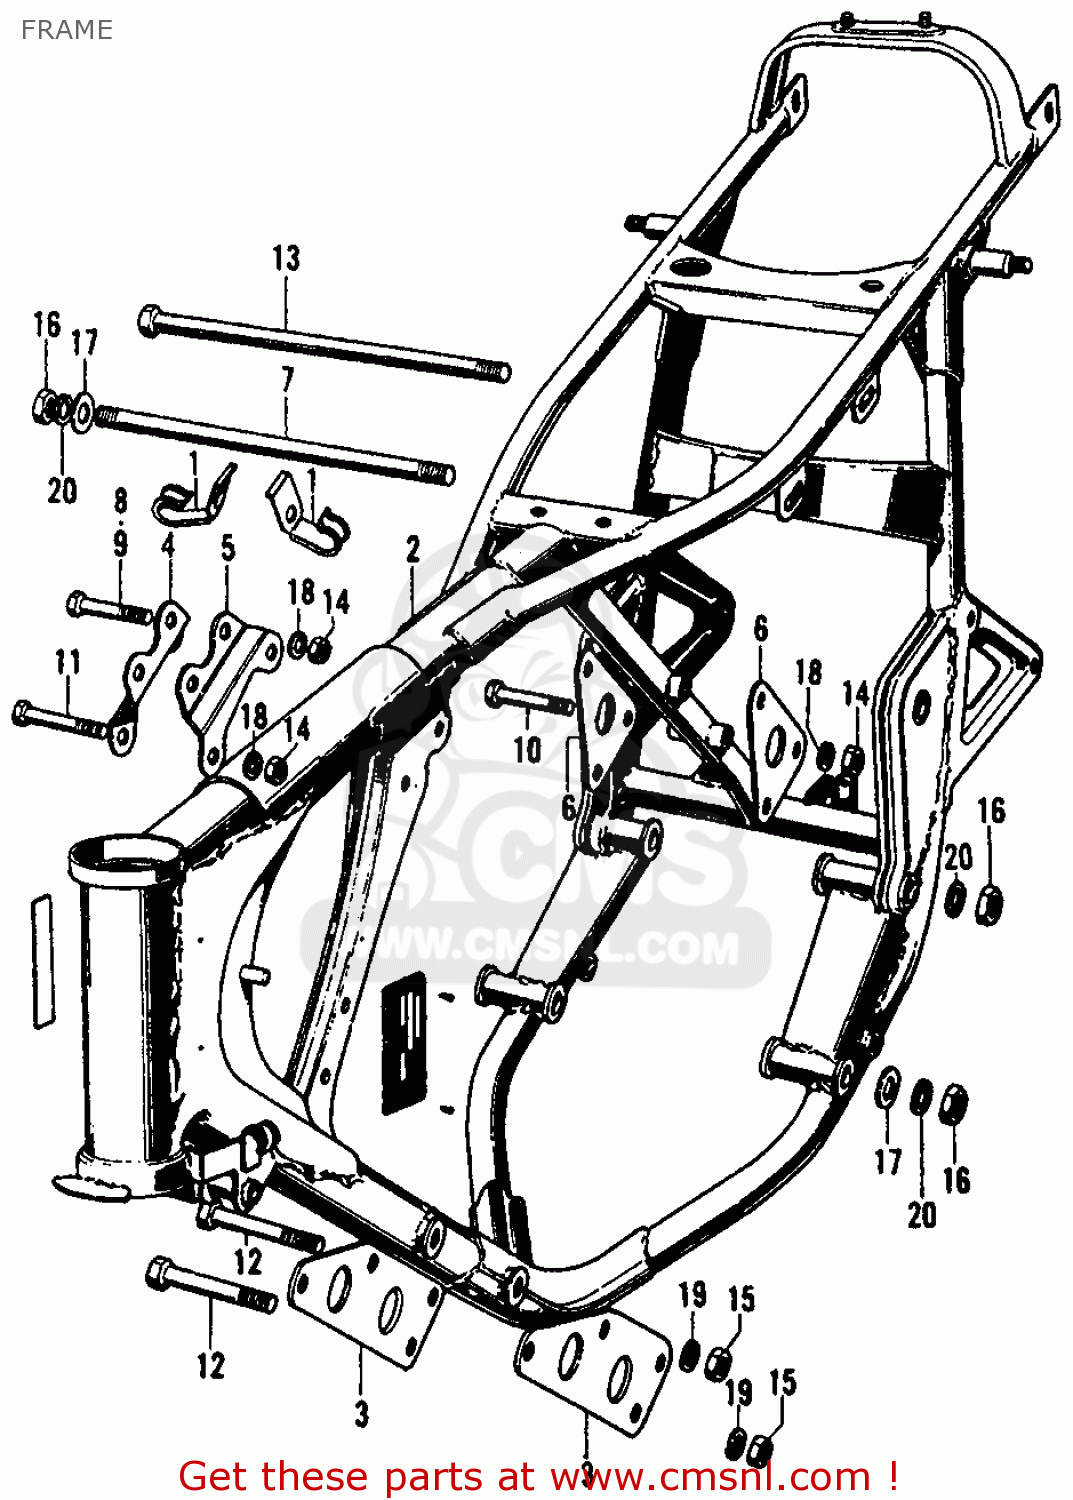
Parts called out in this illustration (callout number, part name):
1	CLAMPER,CORD
3	PLATE, FR. ENGINE
4	PLATE,HANGER
5	PLATE,HANGER
6	PLATE, RR. ENGINE
7	BOLT ENG HANGER
8	BOLT,HEX 8X57
9	BOLT,HEX.8X63
10	BOLT,HEX 8X70
11	BOLT,HEX 8X87
12	BOLT,HEX 10X90
13	BOLT HEX 12X275
15	NUT,HEX.,10M/M
16	NUT,HEX
17	WASHER,PLAIN,12MM
18	SPG-WASHER 8MM
19	SPG-WASHER 10MM
20	WASHER,SPG 12MM
